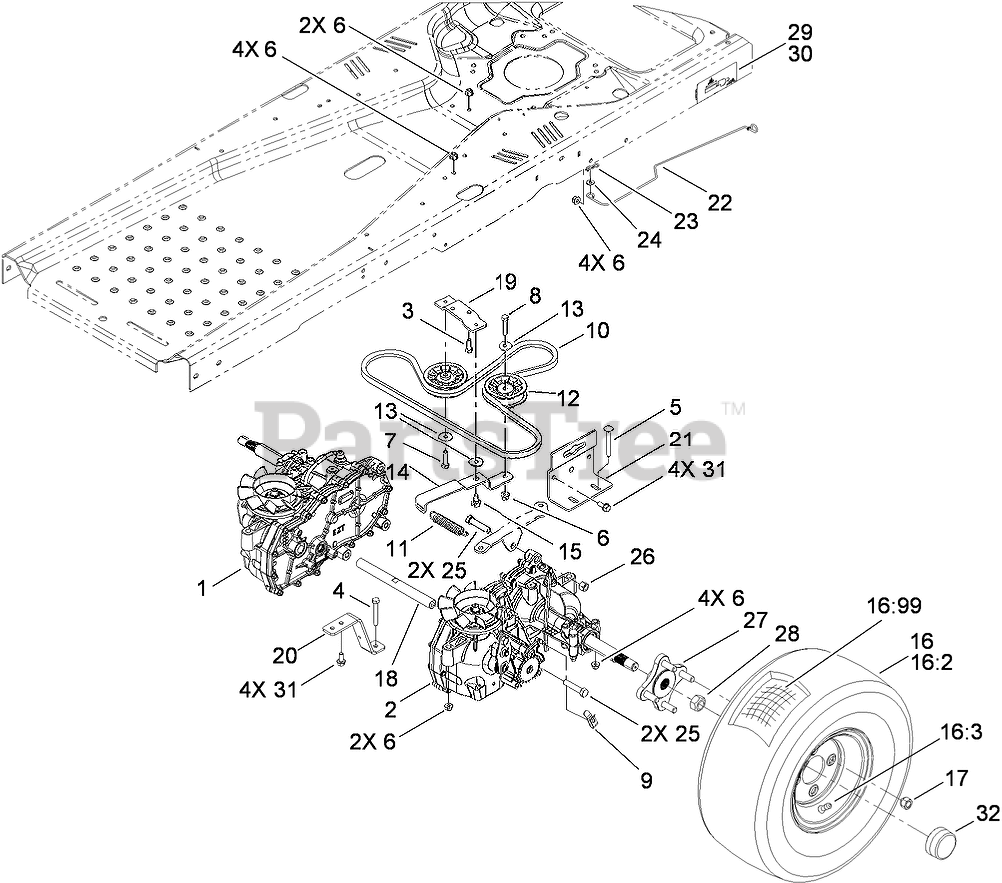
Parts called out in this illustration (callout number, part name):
1	HYDRO-RH
2	HYDRO-LH
3	SCREW-HH
4	SCREW-HH
5	SCREW-CARR
6	NUT-HF, NI
7	SCREW-HH
8	SCREW-HH
9	CLIP-SPRING
10	V-BELT
11	SPRING-IDLER
12	PULLEY-IDLER
13	WASHER-PIVOT
14	ARM-IDLER
15	BOLT-SHOULDER
16	WHEEL AND TIRE ASM
16:2	TIRE
16:3	STEM-VALVE
16:99	TUBE-TIRE
17	NUT-LUG
18	SHAFT-CROSS
19	PLATE-PIVOT
20	STRAP-TORQUE
21	SUPPORT-HYDRO
22	ROD-BYPASS
23	PIN-COTTER
24	WASHER-FLAT
25	SCREW-HH
26	NUT-LOCK, NI
27	HUB ASM
28	NUT-LOCK
29	DECAL-TRANSPORT, LH
30	DECAL-TRANSPORT, RH
31	SCREW-HHF
32	COVER-NUT, AXLE
